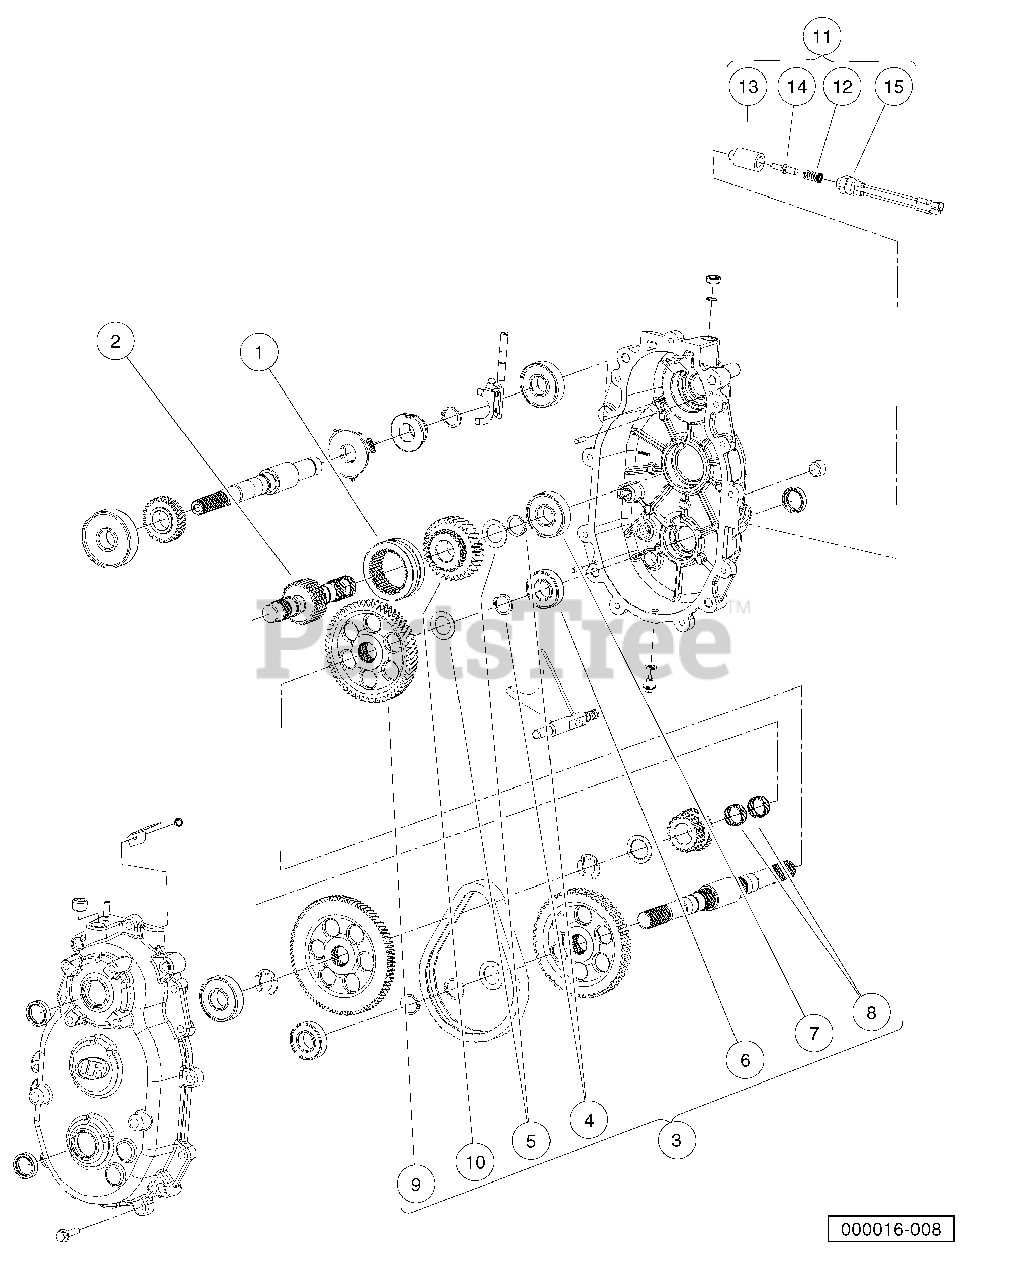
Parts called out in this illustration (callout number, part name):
1	Dog, Engagement
2	Shaft, Intermediate
3	Kit, Forward Gear Repair
4	Ring, Retaining, Basic External
5	Washer, Thrust, 1.007 X .062
6	Bearing, Ball
7	Bearing, Ball
8	Bearing, Needle
9	Gear, Helical 58-Tooth
10	Gear, Helical 34-Tooth
11	Kit, Neutral Switch Repair
12	Spring, .484 X .340 X 1.076
13	Guide, Detent Bullet
14	Bullet, Detent
15	Switch, Indicator, Pollak
